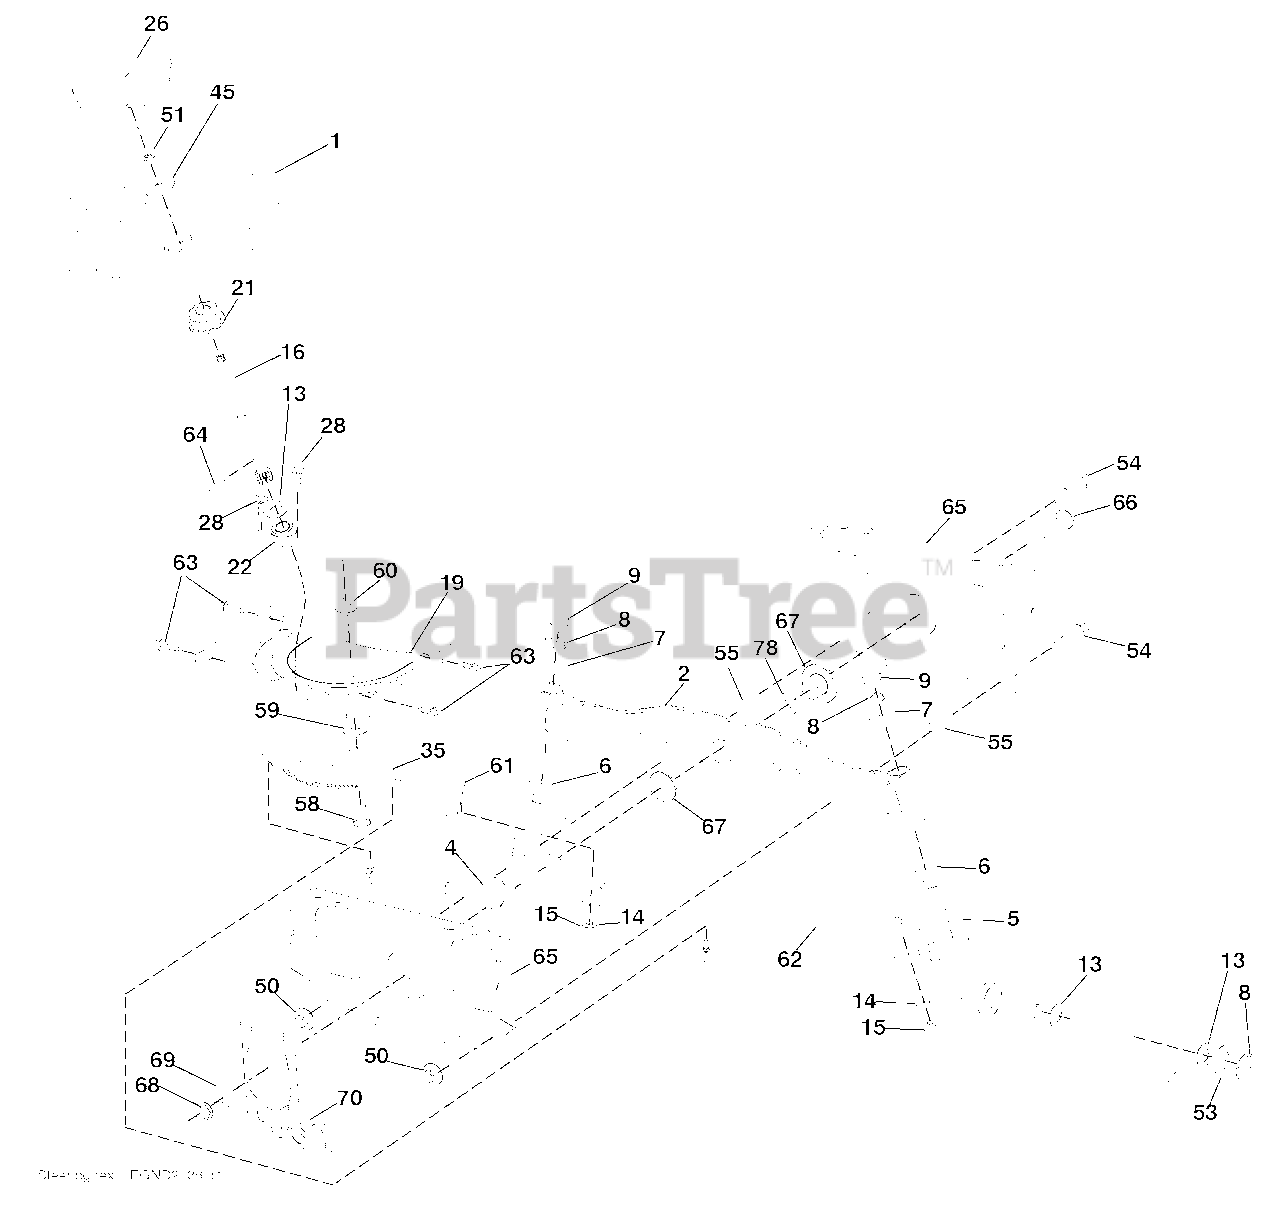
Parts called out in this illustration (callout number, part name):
1	Wheel, Steering
2	Axle Asm., Front
4	Spindle Asm., LH
5	Spindle Asm., RH
6	Bearing, Race Thrust Harden
7	Washer 25/32 x 1-5/8 x 16 Ga.
8	Ring, Clip #T5304-75
9	Cap, Spindle
13	Washer 25/32 x 1-1/4 x 16 Ga.
14	Washer, Lock Hvy Hlcl Spr 3/8
15	Nut, Crown Lock 3/8-24 unf
16	Shaft Steering
19	Plate Steering
21	Adapter, Wheel Steering
22	Steering Supt.
26	Insert, Wheel Steering
28	Screw 3/8-16 x 3/4
35	Gear, Sector Plate
45	Washer 9/16 ID x 2-3/8 OD 12 Ga.
50	Nut Lock Flg 3/8-16
51	Nut Hex Jam Toplock 1/2-20 unf
53	Washer Hardened .793 x 1.637 x .060
54	Bolt Hex HS 3/8-16 x 2-1/4
55	Spacer Brace Axle
58	Bolt Shoulder Sector Pivot CFM
59	Washer Thrust Sector Steering
60	Nut Flange Lock 5/8-11
61	Draglink, LH
62	Draglink, RH
63	Screw 5/16-18 x 3/4
64	Retainer Clip Spring Steering
65	Brace Axle Front
66	Bolt Hex Fghd 7/16-14 x 3 Serr
67	Bushing PM Front Axle
68	Nut Lock Flange 7/16-14 Gr. 5
69	Washer 1.5 x .505 x .118
70	Bracket Deck Susp. Front
78	Washer Thrust 0515 x .750 x .033
